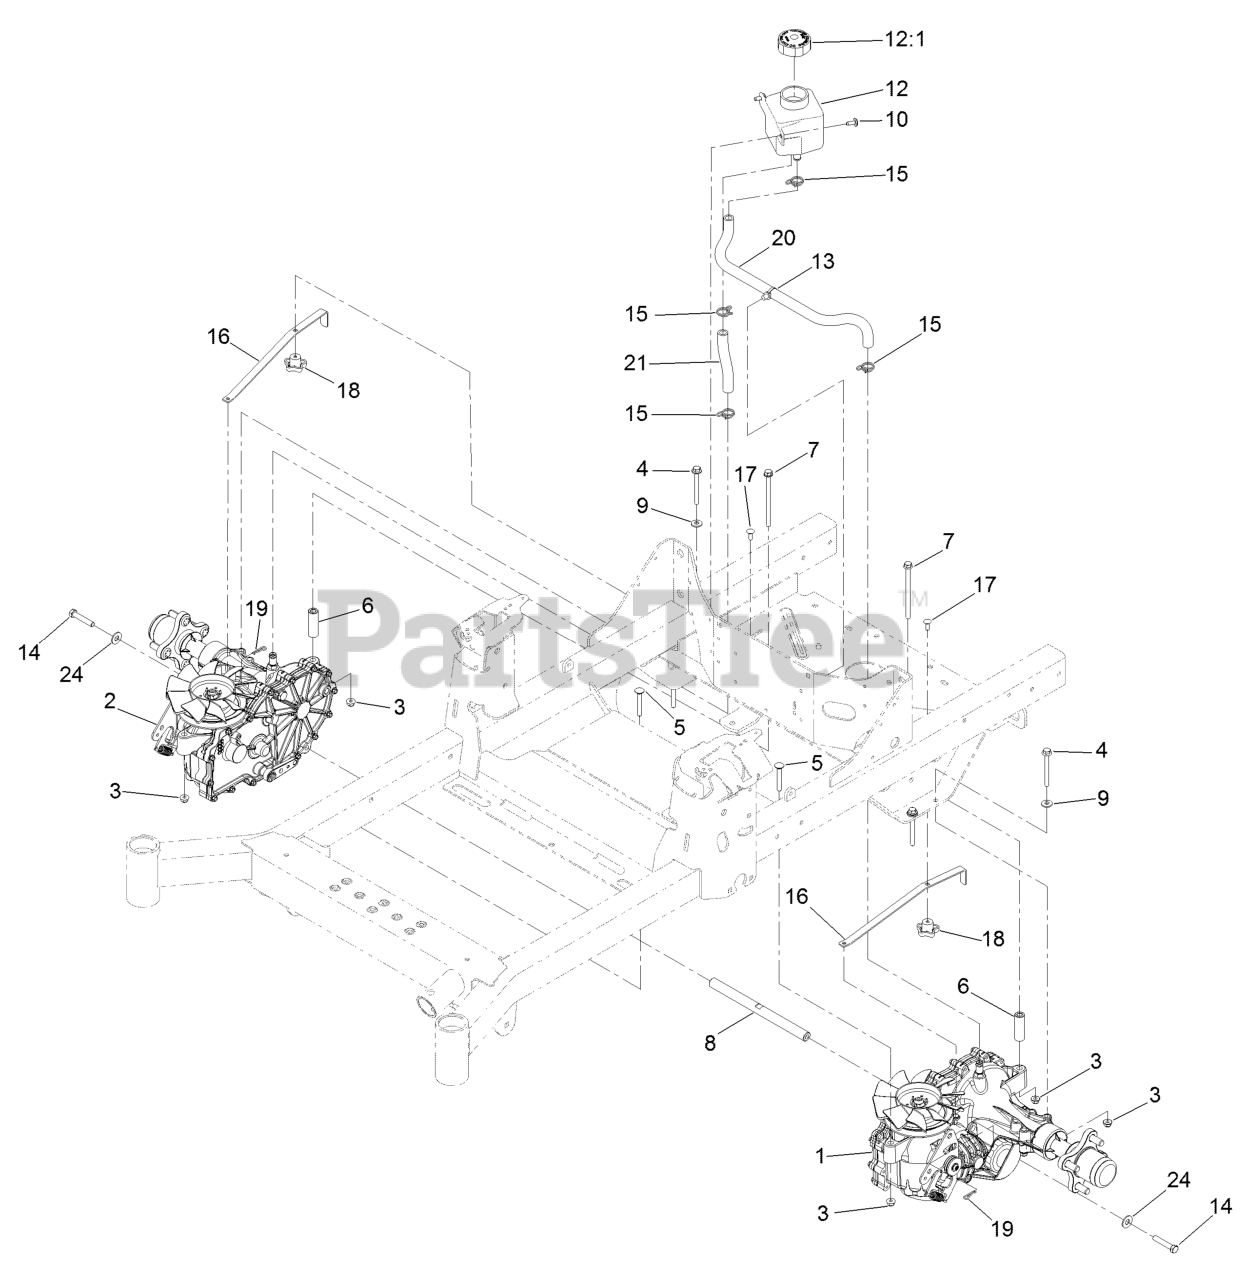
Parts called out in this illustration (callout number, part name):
1	LH Transaxle ASM
2	RH Transaxle ASM
3	Nut-HF, NI
4	Screw-HHF
5	Bolt-CARR
6	Spacer-Hydro
7	Screw HHF
8	Shaft-Spacer
9	Washer-Spring
10	Screw-Torx
12	Tank-HYD
12:1	Cap-Reservoir, HYD
13	Clip-Tie
14	Screw-HH W/Loctite
15	Clamp-Hose
16	Arm-Bypass, Hydro
17	Bolt-CARR
18	Knob-Handle
19	Pin-Cotter
20	Hose-Hydraulic
21	Hose-Hydraulic
24	Washer-Flat
